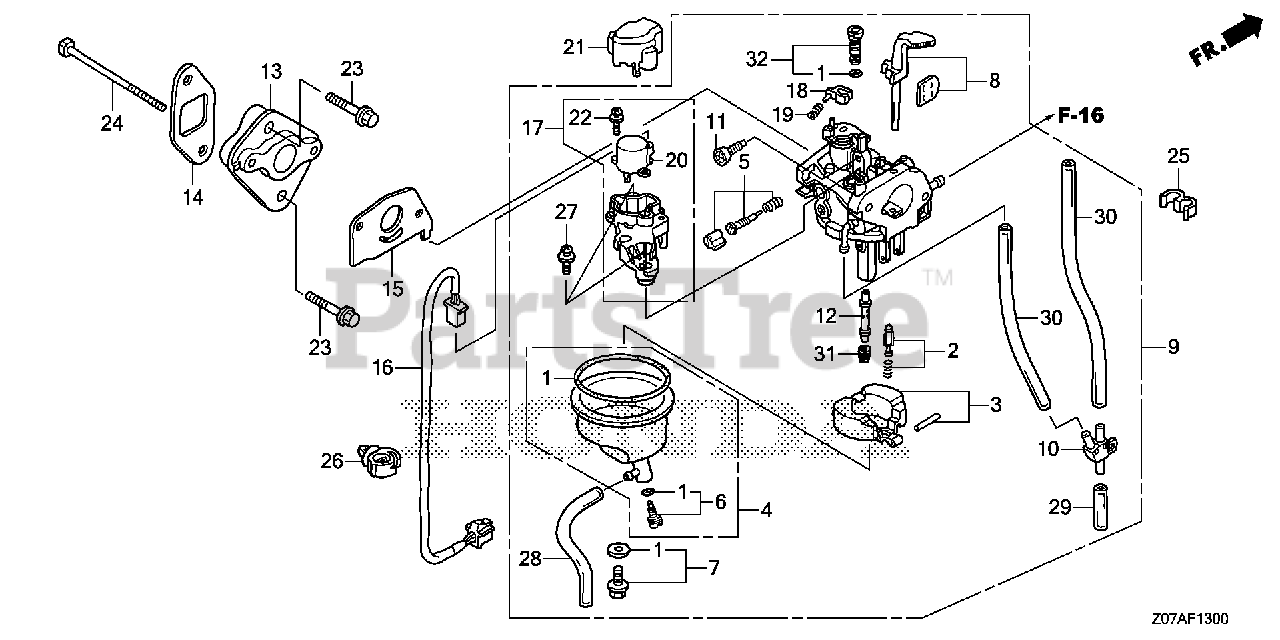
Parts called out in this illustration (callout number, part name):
1	GASKET SET
2	VALVE SET, FLOAT (SEAT NOT INCLUDED)
4	CHAMBER SET, FLOAT
5	SCREW SET, PILOT
6	SCREW SET, DRAIN
7	SCREW SET
9	CARBURETOR ASSY. (BF30E D/E)
10	JOINT, AIR VENT TUBE
11	SCREW, THROTTLE STOP
12	NOZZLE, MAIN
13	INSULATOR, CARBURETOR
14	GASKET, INSULATOR
15	GASKET, CARBURETOR
16	SUB-WIRE ASSY.
17	MOTOR ASSY., THROTTLE CONTROL
18	LEVER, LINK
19	SPRING, COMPRESSION COIL
20	MOTOR, THROTTLE CONTROL
21	COVER, THROTTLE MOTOR
22	SCREW-WASHER (3X8)
23	BOLT, FLANGE (6X25) (NSHF)
24	BOLT, HEX. (5X95)
25	CLAMP, TUBE (7X8)
26	CLIP, WIRE HARNESS (25MM)
27	SCREW-WASHER (4X10)
28	BULK HOSE, VINYL (3.5X6.5X8000) (3.5X6.5X240)
29	BULK HOSE, VINYL (4X7X8000) (4X7X30)
30	BULK HOSE, VINYL (4X7X8000) (4X7X230)
31	JET, MAIN (#58)
31	JET, MAIN (#60)
31	JET, MAIN (#62)
32	JET SET, PILOT (#35)
